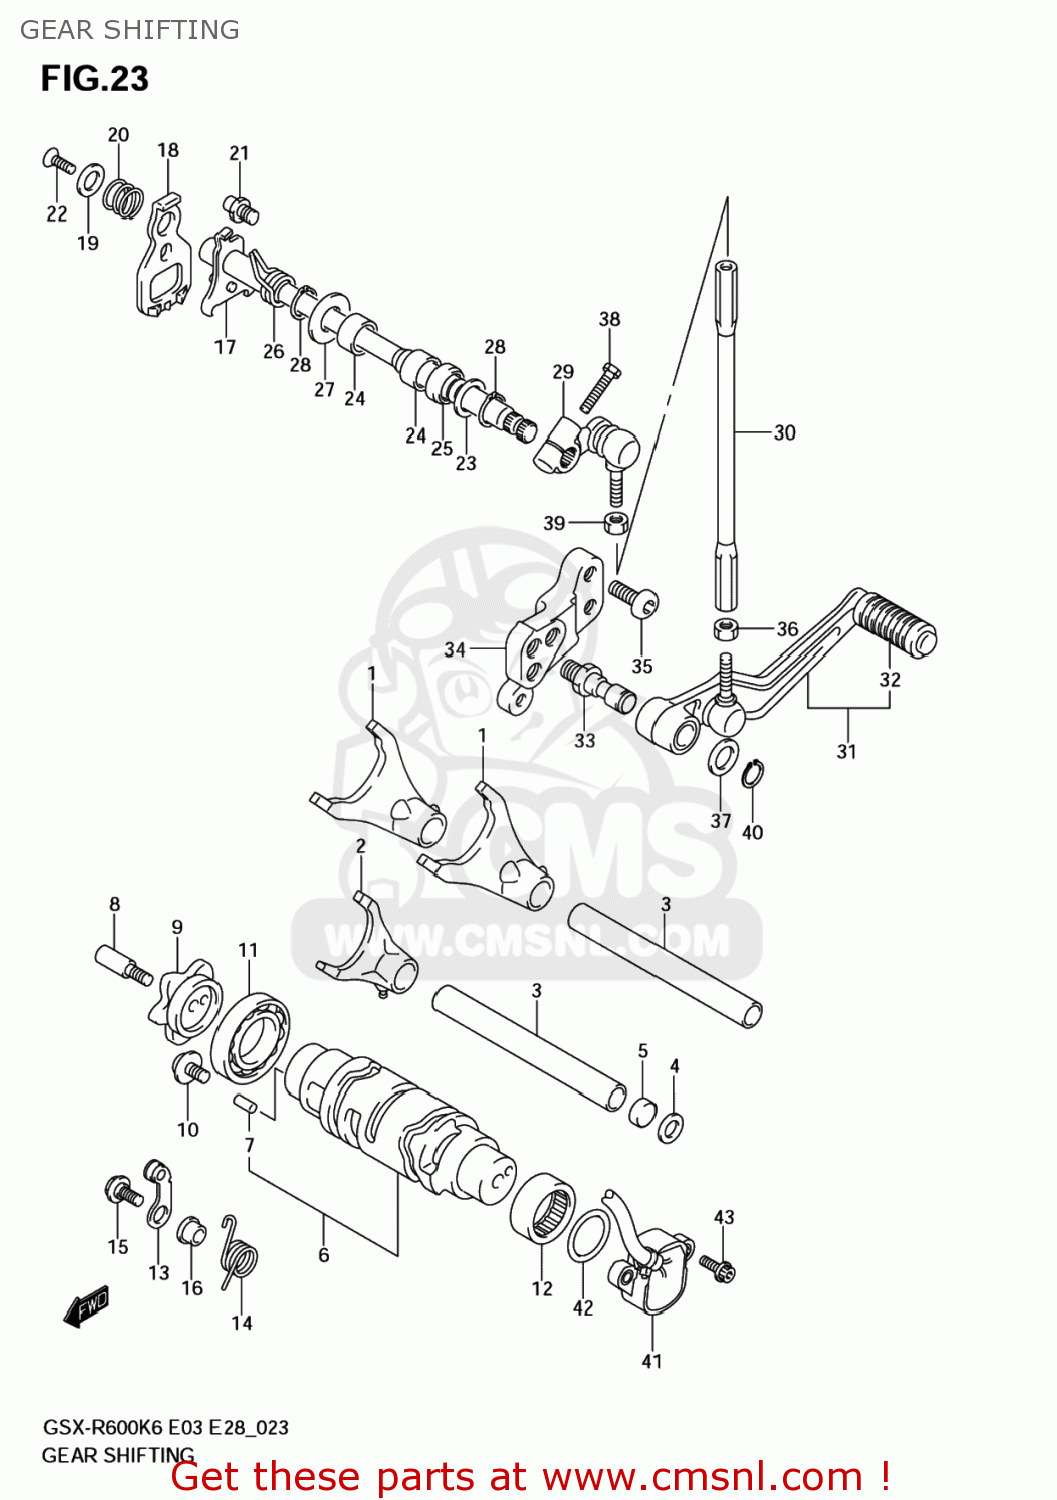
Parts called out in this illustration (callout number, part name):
1	FORK,GEAR SHIF
2	FORK,GEAR SHIF
3	SHAFT,GEAR SHIFT FORK NO.1
4	WASHER. FORK SH
5	PLUG
6	CAM,GEAR SHIFT
7	PIN
8	BOLT,GEAR SHIF
9	PLATE,GEAR SHIFT CAM
10	SCREW
11	BEARING(25X47X8)
12	BEARING(25X32X12)
13	STOPPER,SHIFT CAM
14	SPRING,GEAR SHIFT CAM STOPPER
15	BOLT,SHIFT CAM STOPPER ARM
16	SPACER,CAM STOPPER
17	SHAFT,GEAR SHIFT
18	PLATE,GEAR SHIFT CAM DRIVE
19	WASHER,GEAR SHIFT SHAFT END
20	SPRING,GEAR SHIFT PLATE RETURN
21	STOPPER,GEAR SHIFT ARM
22	SCREW,6X16
23	WASHER(14X29X0.8)
24	BEARING(14X20X12)
25	SEAL,OIL(14X22X6)
26	SPRING
27	SHIM(14X22X1)
28	CIRCLIP
29	ARM,GEAR SHIFT LINK
30	ROD,GEAR SHIFT LINK
31	LEVER ASSY,GEA
32	RUBBER,GEAR SHIFT PEDAL
33	SHAFT,GEAR SHIFT LEVER
34	BRACKET,GEAR SHIFT LEVER
35	BOLT(8X20)
36	NUT
37	WASHER(12.5X20X1)
38	BOLT
39	NUT
40	CIRCLIP
41	SENSOR ASSY,GE
42	O RING(D:2.4,ID:25.7)
43	BOLT(5X16)
